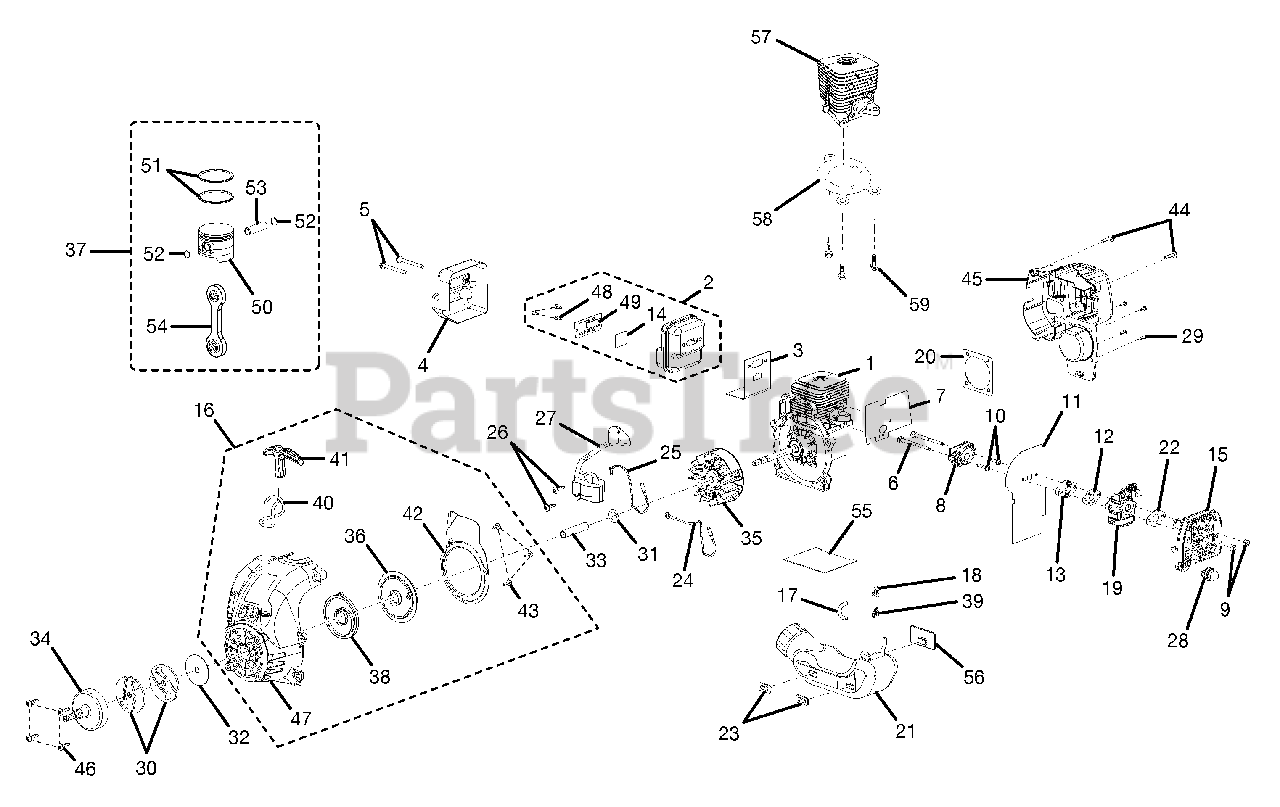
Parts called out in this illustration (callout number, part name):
1	SHORT BLOCK ASSEMBLY
2	MUFFLER ASSEMBLY
3	MUFFLER GASKET
4	HEAT SHIELD
5	SCREW (10-24 X 2-1/8 IN.TORX TRUSS HD. SEMS)
6	BOLT (10-27 X 2-3/8 in. HEX HD.)
7	HEAT DAM GASKET
9	LOCK NUT (10-24)
10	SCREW (10-24 X 1 in. TORX PAN HD. SEMS)
11	CARBURETOR GASKET
12	CARBURETOR GASKET
15	AIR FILTER BOX
16	COMPLETE STARTER ASSEMBLY
17	RUBBER TUBING (2 in.)
19	CARBURETOR
20	GASKET, C/C COVER
21	FUEL TANK W/CAP ASSEMBLY
24	LEAD W/TERMINALS
26	SCREW (8-32 X 1 in. THREAD FORMING)
27	IGNITION MODULE (W/ 3 SEC. KILL)
28	PRIMER ASSEMBLY
29	SCREW (10-24 X 3/4 in. PAN HD. TORX)
32	WASHER
34	DRUM & CONNECTOR
35	ROTOR PAWL ASSEMBLY
36	STARTER PULLEY
37	PISTON ASSEMBLY
38	SPRING & CONTAINER
40	STARTER ROPE
41	STARTER GRIP
43	SCREW (8-16 X 1/2 in. THD. FORM. )
44	SCREW (10-14 X 7/8 in. THD. FORM. )
45	REAR HOUSING
46	SCREW (10-24 X 3/4 in. TRUSS HD.)
47	STARTER HOUSING W/EYELET
48	SCREW (6-20 X 1/4 IN. TRI-LOBULAR)
49	OUTLET TUBE
50	PISTON W/PIN
51	PISTON RING 30cc
52	RETAINING RING
53	PISTON PIN
54	CONNECTING ROD ASSEMBLY
55	TANK INSULATION GASKET
56	RUBBER BUMPER
57	CYLINDER
58	CYLINDER GASKET
58	SCREW (12-24 X 5/8 in.)
